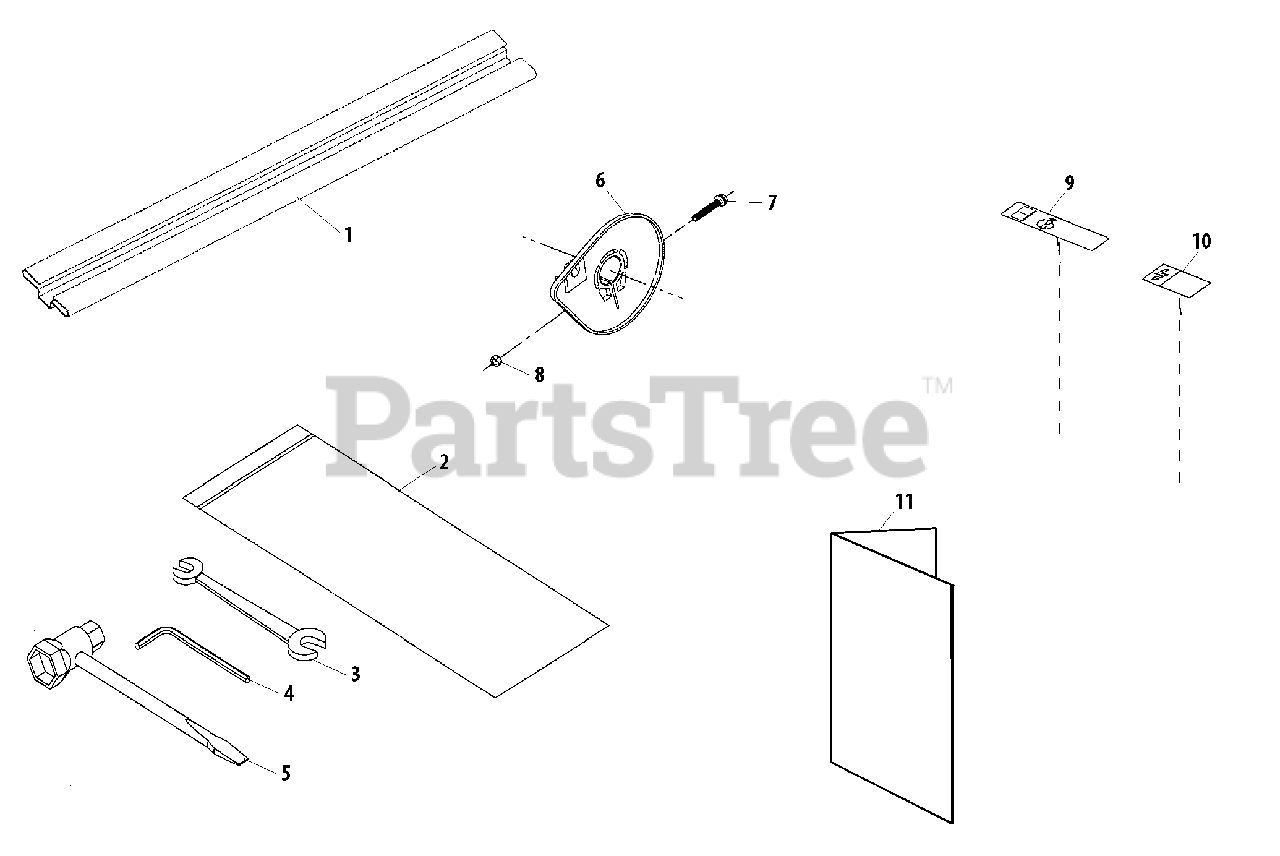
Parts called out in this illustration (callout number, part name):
1	COVER, BLADE
2	BAG, TOOL
3	SPANNER - 8X10mm
4	HEX KEY - 4mm
5	T-WRENCH
6	PROTECTOR
7	SCREW - 5X30
8	NUT - 5
9	LABEL - CAUTION
10	LABEL - HIGH VOLTAGE
11	OWNER'S MANUAL
